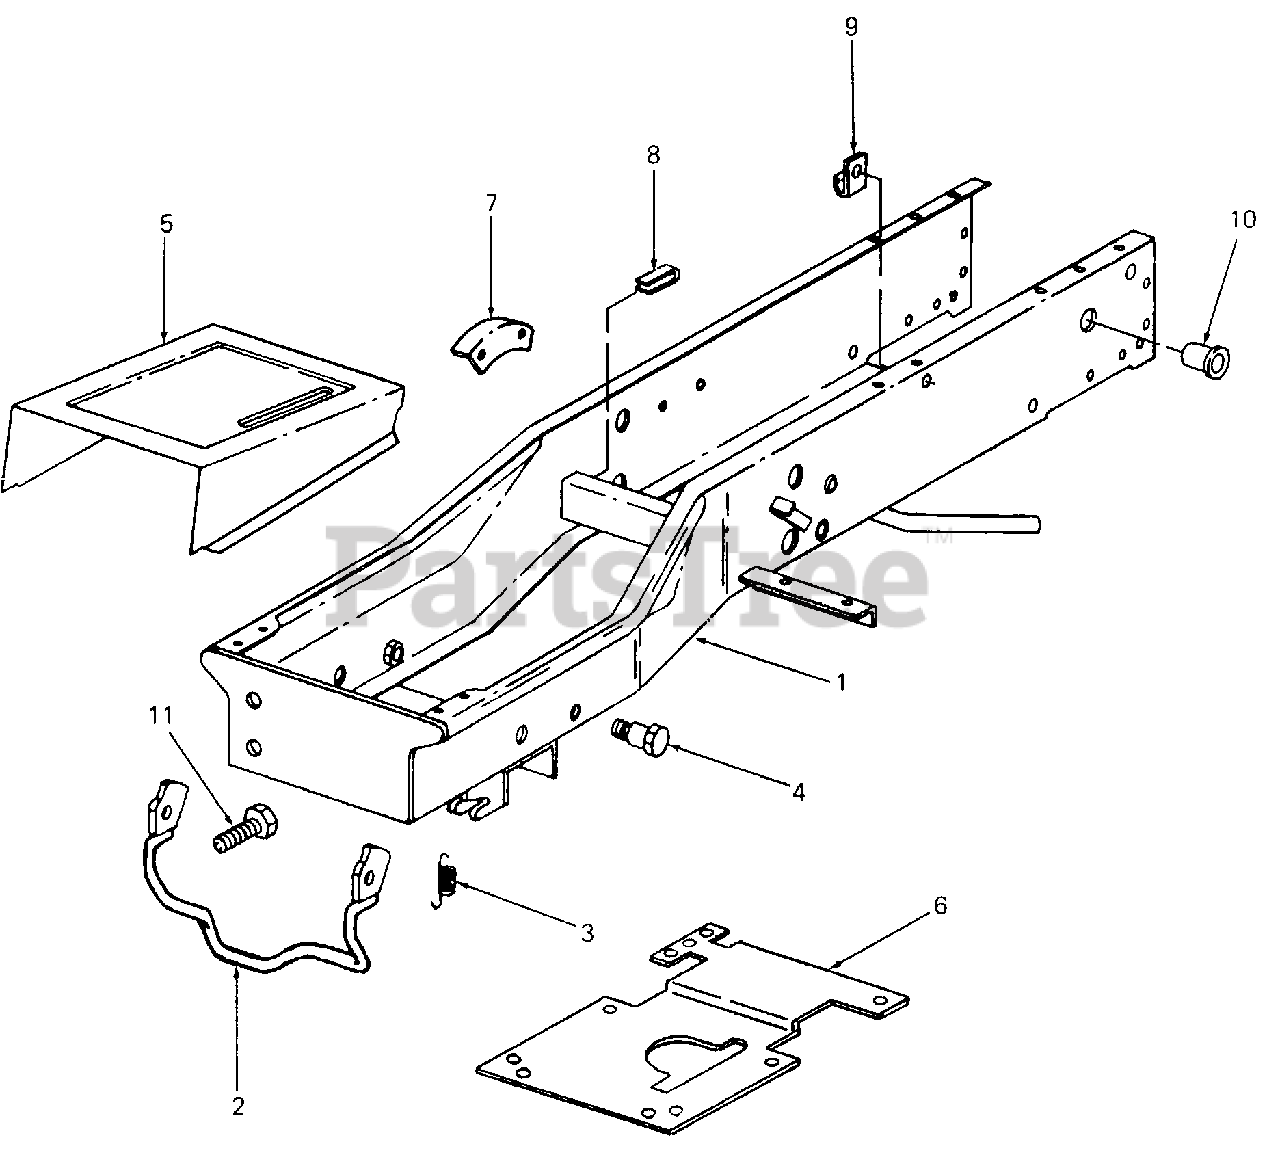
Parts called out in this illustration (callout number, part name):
2	Latch Assy, Quick
3	Spring, Latch
4	Bolt, Shoulder
5	Cover, Frame w/Graphic
7	Bracket, Height Indicator
8	Clip, Steering Bracket Cable
9	Clip, Cable
10	Bushing, Snap
11	Screw, Adjustment, 1/2-20 X 1.0 Lg GR5
